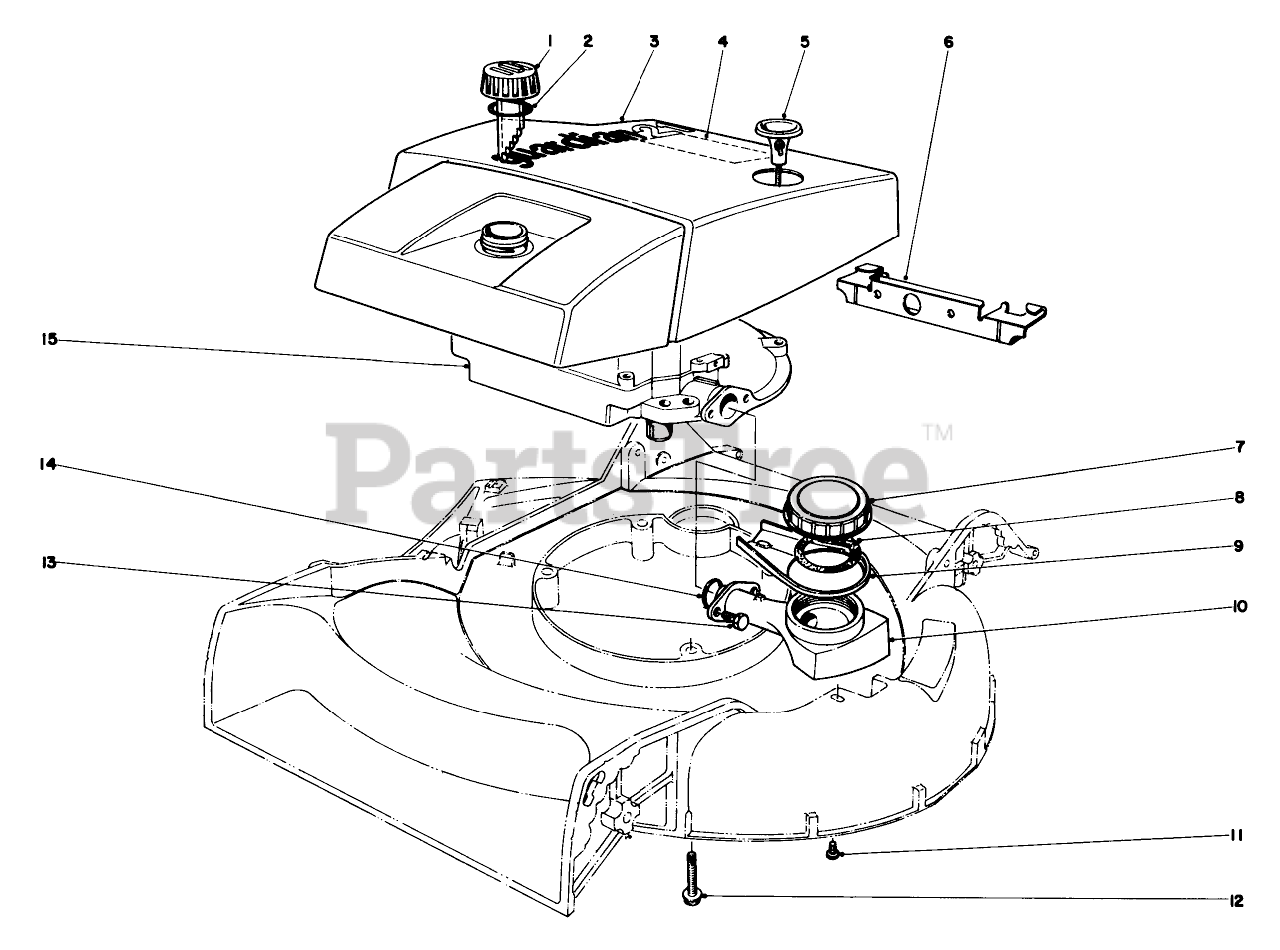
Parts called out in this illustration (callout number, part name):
2	Gasket
4	Decal-Maintenance
6	Shroud Bracket
10	Oil Gauge
12	3/8-16 X 2-3/4 CAPSCR
13	SCREW-HH
14	O RING
15	Engine
